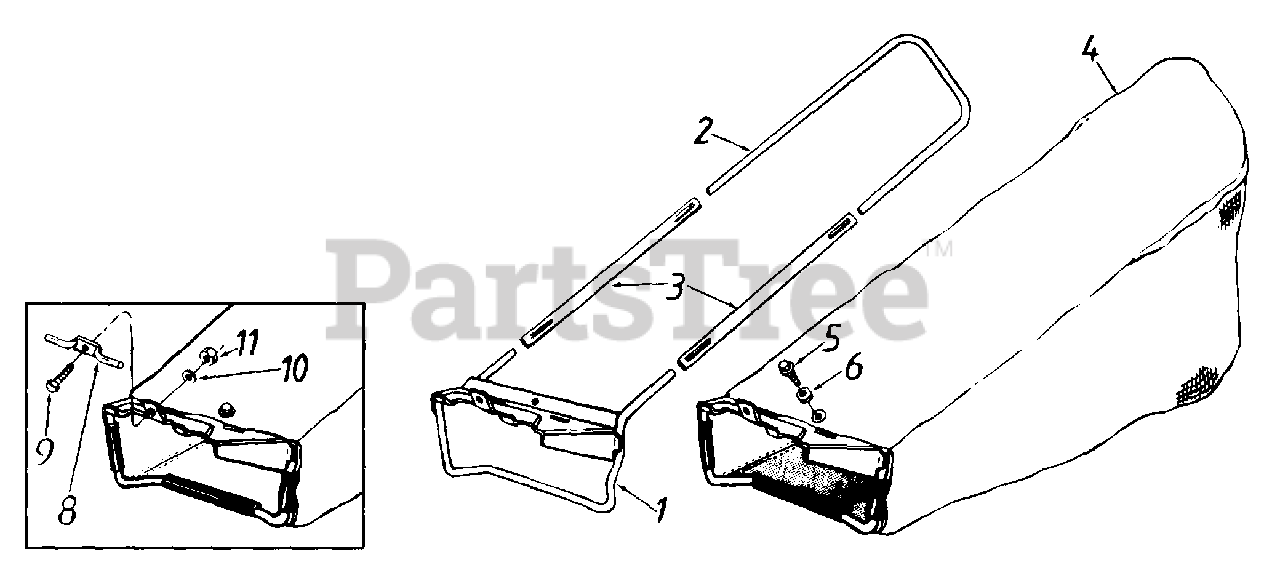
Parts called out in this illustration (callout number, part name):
4	Grass Bag
5	Hex Wash. Hd. TT-Tap Scr. 1/4-20 x 5" Lg.
6	Bell-Wash. 1/4" I.D.
8	Grass Bag Hook
9	Hex Bolt 1/4-20 x .62" Lg.
10	L-Wash. 1/4" I.D.
11	Hex Nut 1/4-20 Thd.
